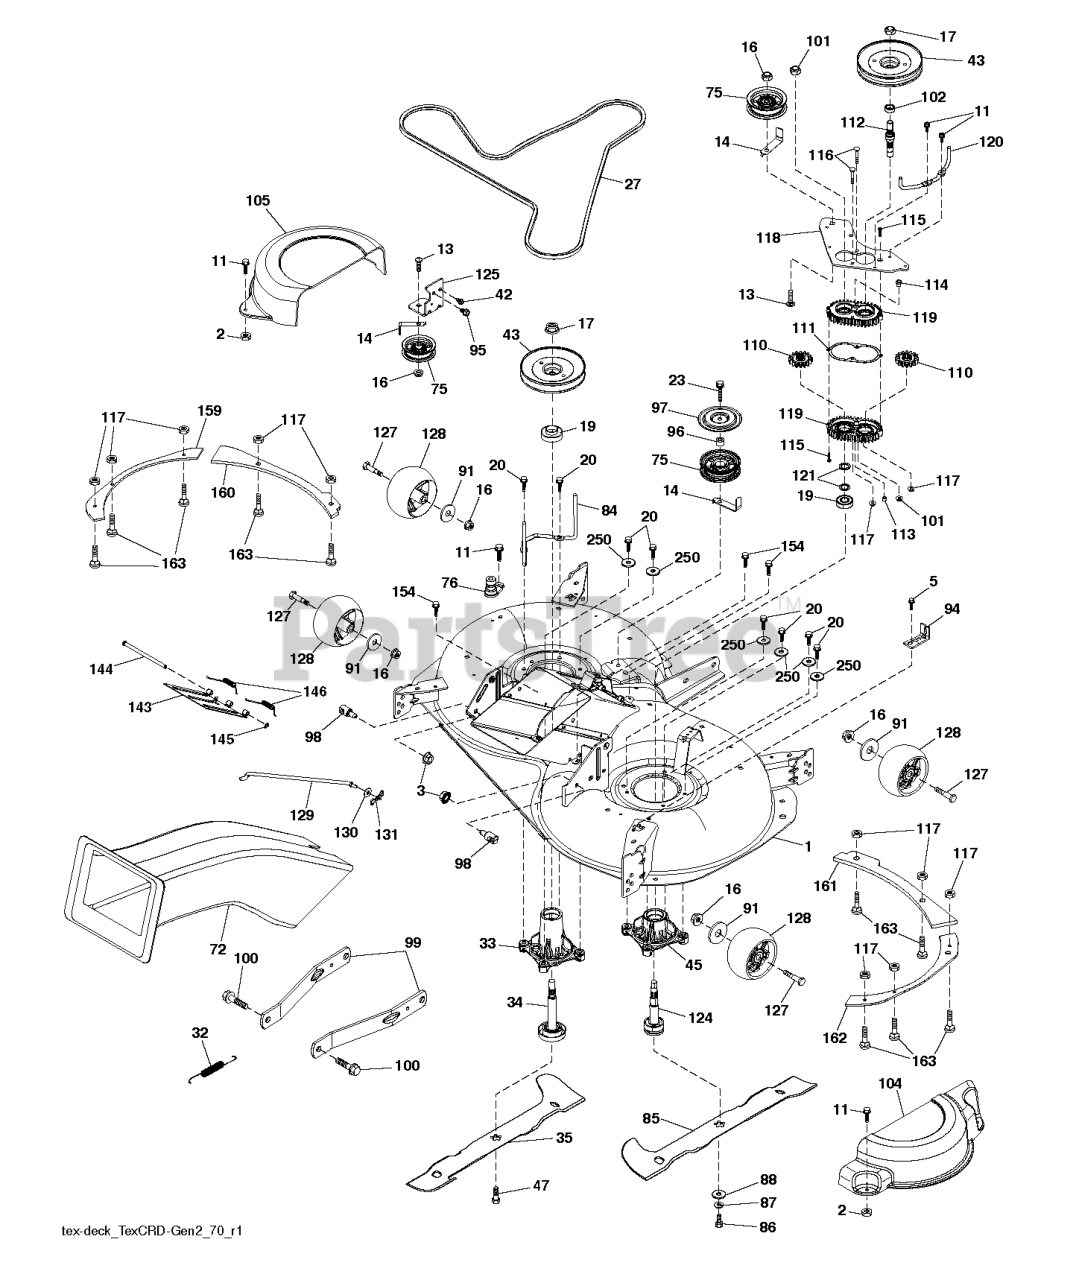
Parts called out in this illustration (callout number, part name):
1	DECK SVC 107HP.EZMUL.498
2	PALNUT 1/4
3	NUT LOCK HEX FLANGE 5/16-18
5	BOLT.5/16HEX.WHS.HD
11	SCREW.1/4-20X5/8
13	BOLT.3/8-16X1.50
14	KEEPER, BELT IDLER
16	NUT LOCK FLG 3/8-16 UNC
17	NUT.FLANGE.LOCK.TOP
18	WASHER.SPACER.MANDREL
20	SCREW, WASHER HEAD
23	SCREW LT
27	BELT BELT. ELECTRIC MOWER DRIV
32	SPRING 107CM & 97CM ELECTRIC D
33	RP.HOUSG.MAND.REV.TALL.N/GRS
34	RP.SAFT ASM.REV.TALL.N/GREASE
35	BLADE.107.LH.SINGLE.NON.QD
36	BOLT.WASHER.ASM.7/16-2
42	SCREW
43	PULLEY PULLEY MANDREL 5.438 PD
45	RP HOUSING.MANDREL.REV.REVS.
72	RP.CHUTE 107/97 TEX GENII
75	FLAT IDLER PULLEY
76	PORT.WASHOUT
84	KEEPER KEEPER. LH MANDREL BELT
85	BLADE.107.RH.SINGLE.NON.QD
87	LOCKWASHER
88	WASHER.BLADE
91	WASHER
94	BRKT.CLUTCH.CABLE
95	SCREW, 3/8-16X3/4
96	SPACER
97	PROTECTOR
98	STUD.FASTNER.W/ANTI-ROTATE
99	ARM.SUSPENSION.MOWER.R
100	BOLT.SHOULDER
101	NUT.CROWNLOCK.9/16 -18.UNC
102	SPACER BEARING
104	COVER.MANDREL.107.RH.GEN.2
105	COVER.MANDREL.107.LH.GEN.2
110	CRD.SPUR.GEAR
111	GASKET GASKET GEARCASE
112	SHAFT SHAFT. CRD GEARCASE ADAP
113	PLUG PLUG OIL
114	VALVE VALVE RELIEF
115	SCREW
116	BOLT.CARIGE.SS.1/4-20X1.75GR5
117	NUT T
118	ARM ARM. CLUTCHING 107 TEX CRD
119	GEARCASE GEARCASE SUBASM
120	KEEPER KEEPER. RH MANDREL BELT
121	WASHER WASHER
124	SUB.ASM.REVERSE.THREAD.REV
125	BRACKET
127	BOLT.SHOULDER.3/8-16X3-5/8.
128	RP WHEEL. GUAGE RALLY
129	ROD ROD. SWAY CRD GEN II
130	WASHER
131	PIN.COTTER.5/16.BOW TI
143	COVER DOOR.107 CM CRD EZ MULCH
144	PIN PIN.HINGE
145	E-RING.5/16"
146	SPRING SPRING: EZ MULCH DOOR
154	SCREW T-30 1/4-20 X
159	PLATE.107CRD.LH.SIDE.BLTON
160	PLATE.107CRD.LH.FRONT.BOLT-ON
161	PLATE.107CRD.RH.FRONT.BOLT-ON
162	PLATE.107CRD.RH.SIDE.BOLT-ON
163	BOLT
